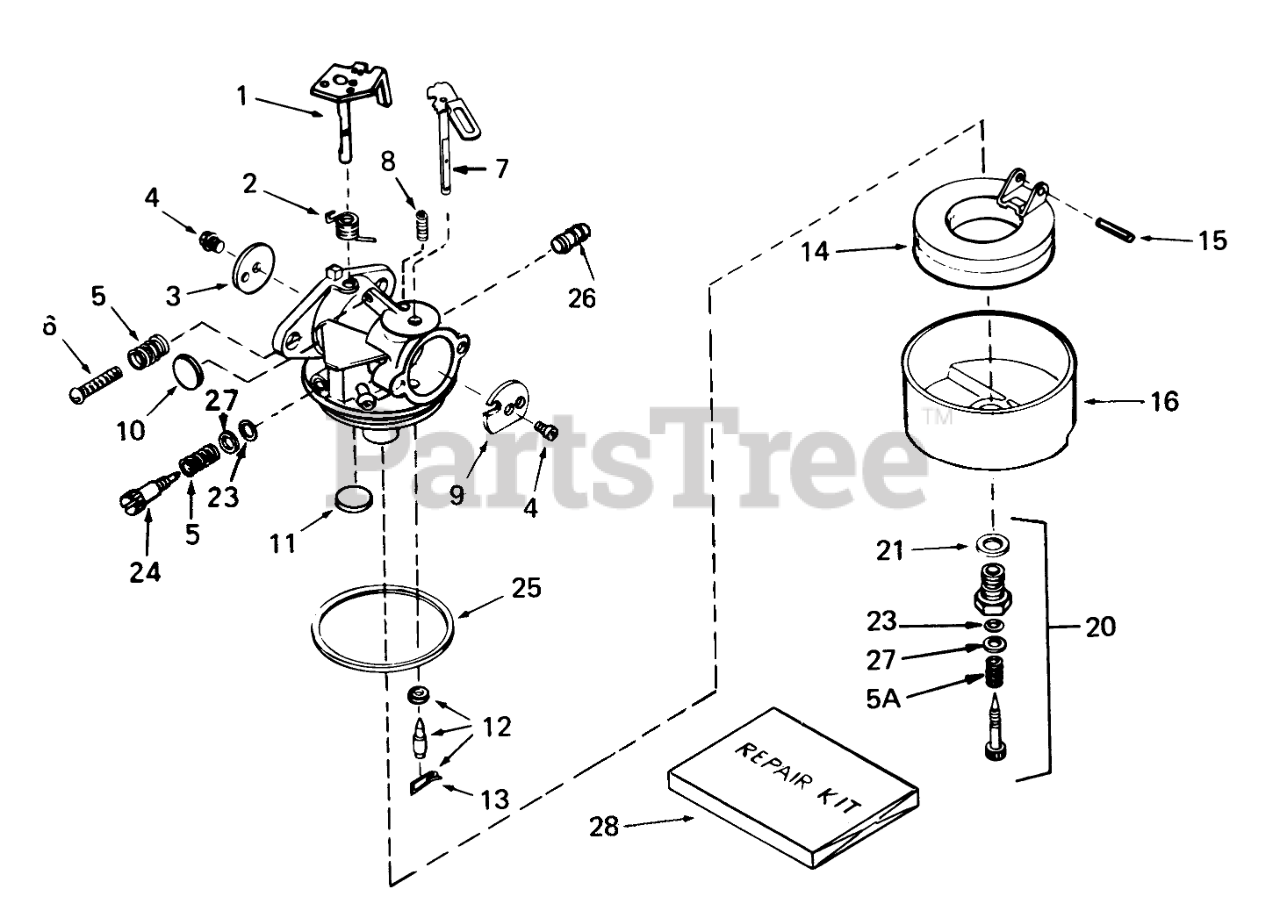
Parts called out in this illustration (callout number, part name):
1	Shaft/Lever-Throttle
2	Spring-Return, Throttle
3	Shutter-Throttle
4	Screw-Shutter
5	Spring-Tension
6	Screw-Throttle Crack Screw / Idle Speed
7	Choke Shaft and Lever ASM
8	Spring-Positioning, Choke
9	Shutter, Choke
10	Plug-Welch, Idle Mixture Well
11	Plug-Welch, Atmospheric Vent
12	Inlet Needle, Seat & Clip Assy. (Incl. Ref. #13)
13	Clip-Spring
14	Float
15	Shaft-Float
16	Bowl-Float (no drain)
20	Adjustment Screw Assy., Main (Incl. Ref. #5A, 21, 23 & 27)
21	Washer-Bowl Nut
23	"O"Ring
24	Screw Main Adjustment
25	O Ring-Bowl, Float
26	Fuel Fitting
28	Repair Kit
